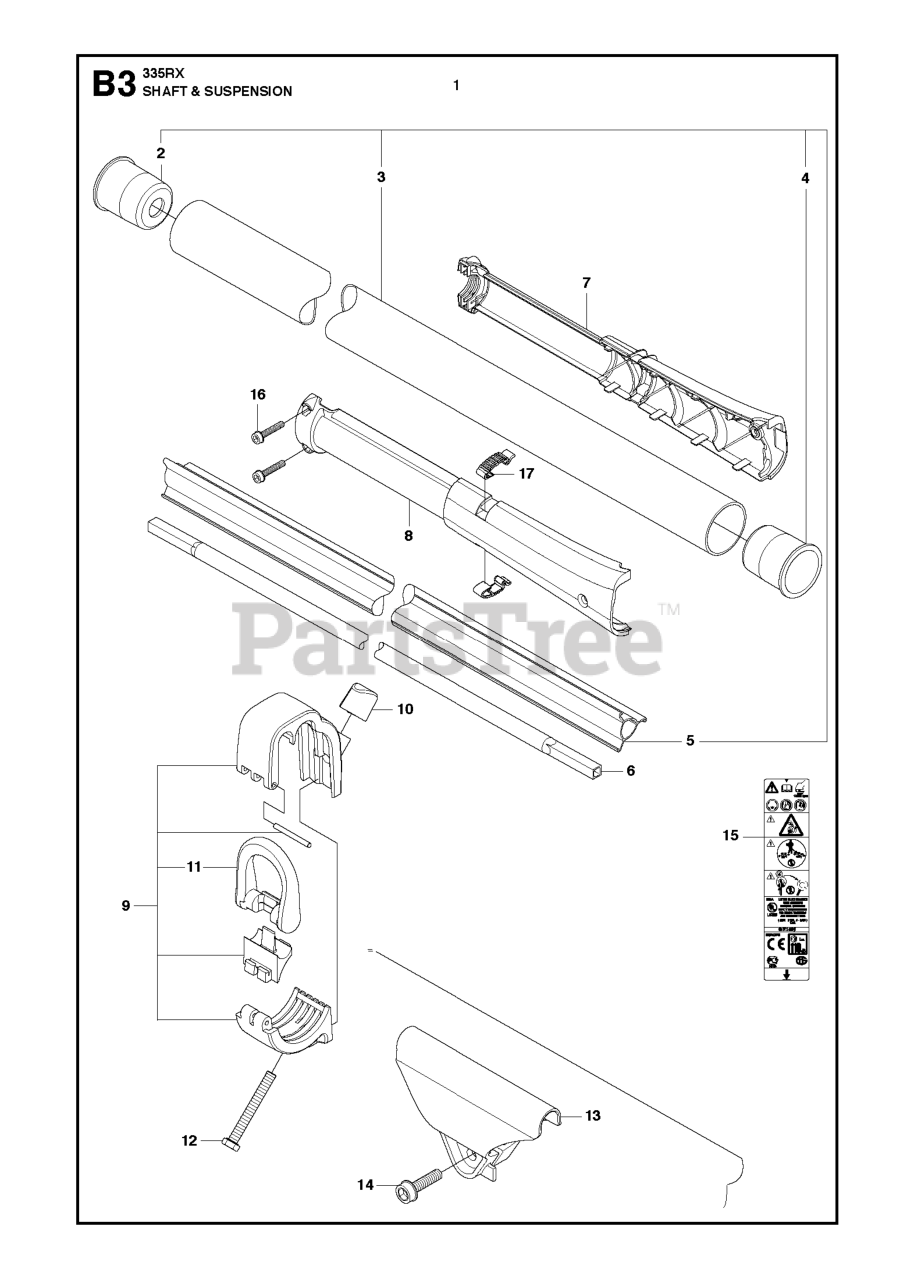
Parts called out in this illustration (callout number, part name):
1	TUBE
2	PLUG
3	TUBE
5	GUIDE
6	SHAFT
7	WEAR PROTECTION RIGHT
8	WEAR PROTECTION LEFT CPL
12	SCREW M6S 5X40
13	CABLE HOLDER
15	RP WARNING DECAL
